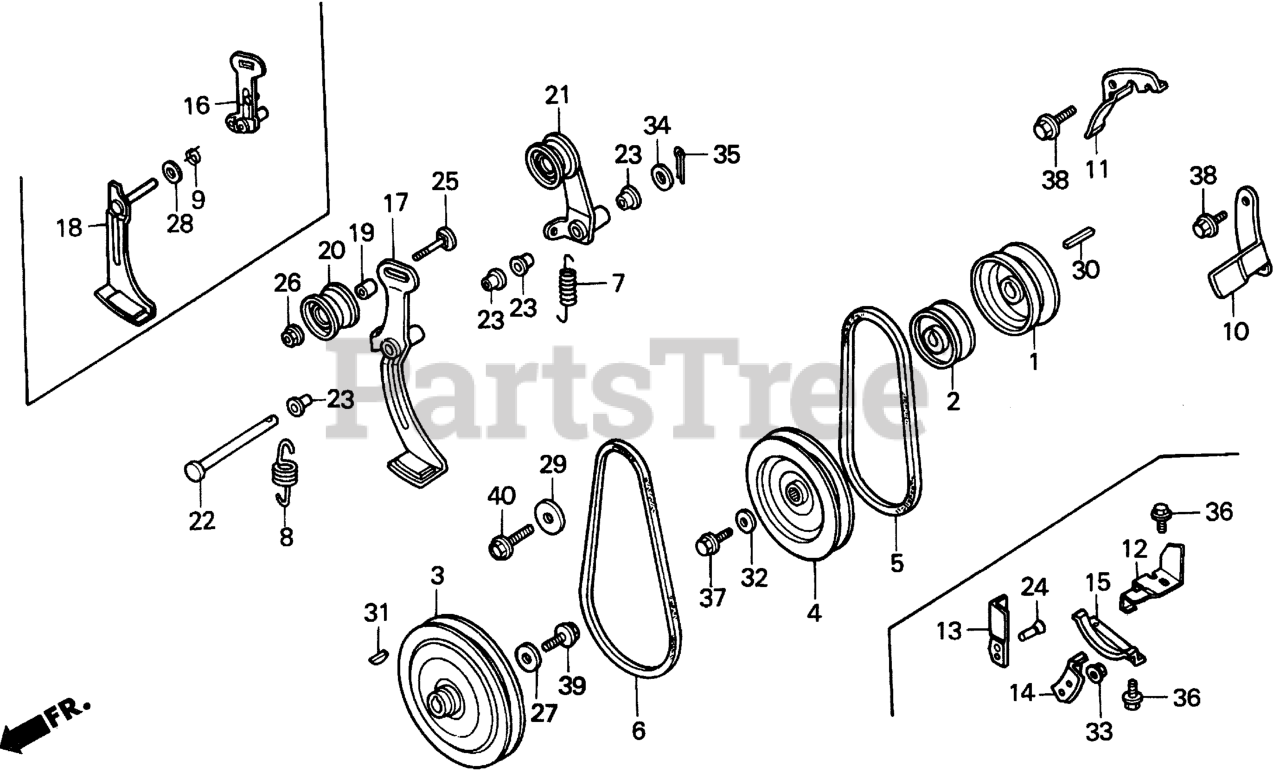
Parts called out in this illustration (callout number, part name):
1	PULLEY, WHEEL DRIVEN
2	PULLEY, AUGER DRIVE
3	PULLEY, AUGER DRIVEN
4	PULLEY, WHEEL DRIVEN
5	V-BELT (SA-32)
6	V-BELT (LB-33)
7	SPRING, TENSIONER RETURN (WHEEL) (NOT AVAILABLE)
8	SPRING, AUGER TENSIONER RETURN
9	SPRING, BRAKE ARM
10	STOPPER, R. BELT
11	STOPPER, L. BELT (R. SIDE)
12	GUIDE, BELT
13	STOPPER, L. BELT
14	STOPPER, R. BELT
15	STOPPER, BELT (WHEEL)
16	ARM, AUGER TENSIONER
18	ARM, AUGER BRAKE
19	COLLAR, ROLLER
21	ARM, WHEEL TENSIONER
23	BUSH, TENSIONER ARM
24	BOLT, DOOR LOCK STRIKER
25	BOLT, ROLLER
26	NUT, SELF-LOCK (8MM)
27	WASHER, SPECIAL (28X8.5X4.0)
28	WASHER, BRAKE ARM
29	WASHER, LOCK (8MM)
30	KEY (7X7X33)
31	KEY, SPECIAL WOODRUFF (16X12)
32	WASHER, CAMSHAFT SIDE
33	NUT, FLANGE (6MM)
34	WASHER, PLAIN (12MM)
35	PIN, COTTER (3.0X18)
36	BOLT, FLANGE (6X12) Use up to Engine SN 1543277.
37	BOLT, FLANGE (6X16)
38	BOLT, FLANGE (8X16) Use from Engine SN 1000016.
39	BOLT, FLANGE (8X16) Use from Engine SN 1000016.
39	BOLT, FLANGE (8X22) Use from Engine SN 1609607.
40	BOLT, FLANGE (8X28)
